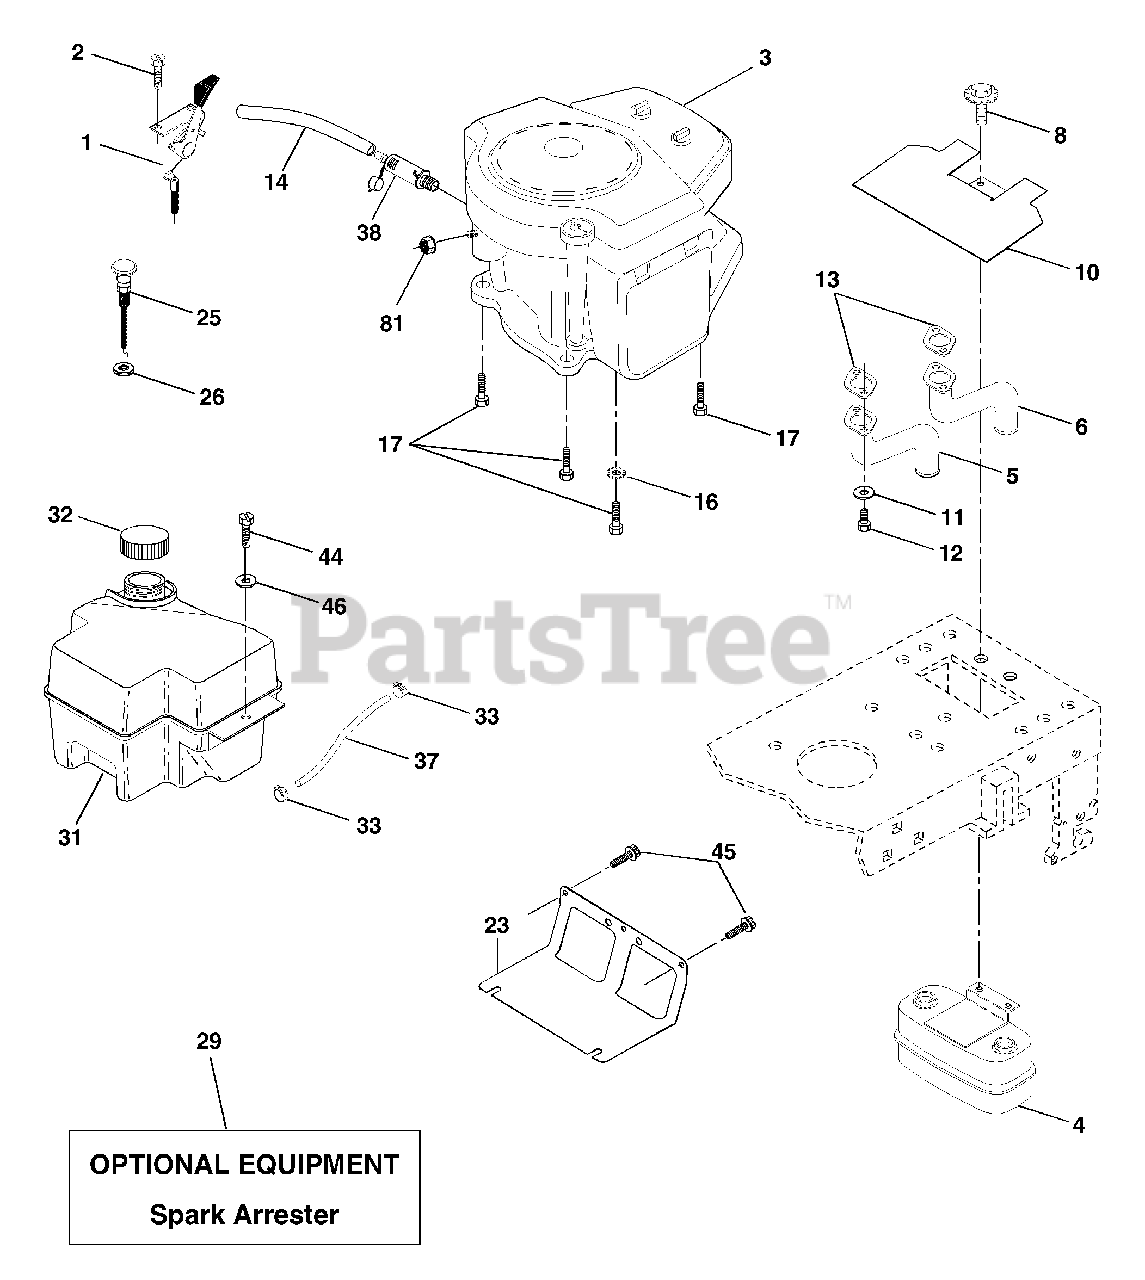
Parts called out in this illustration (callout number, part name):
1	Control Throt
2	Screw Hex Thd Cut 1/4-20x5/8 T
4	Muffler Exhaust
5	Exhaust Asm. Lh
6	Exhaust Asm. Rh
8	Bolt 5/16-18unc x 3/4 w/sems
10	Heat Shield Lt
11	Washer Lock Hvy. Helical 1/4
12	Screw Hex Hd Cap 5/16-18 x 3/4
13	Gasket Muffler
14	Tube Drain Oil Easy
16	Washer Lock Ext Tooth 3/8
17	Screw Thdrol 3/8-16x1-1/2 Tytt
23	Shield BRN/DBR Guard
25	Control Choke
26	Nut Keps 3/8-24 UNF
29	Arrestor Spark
31	Tank Fuel
32	Cap Fuel
33	Clamp Hose Blk
37	Line Fuel
38	Plug Drain Oil Easy
40	Bushing Snap Nyl Black
44	Screw Hexwsh Thdrol 1/4-20 x 3/4
45	Screw Hex wsh Thdrol 3/8-16 x 3/4
46	Washer 9/32 x 7/8 x 16 Ga.
81	Nut Keps Hex 1/4-20 unc
